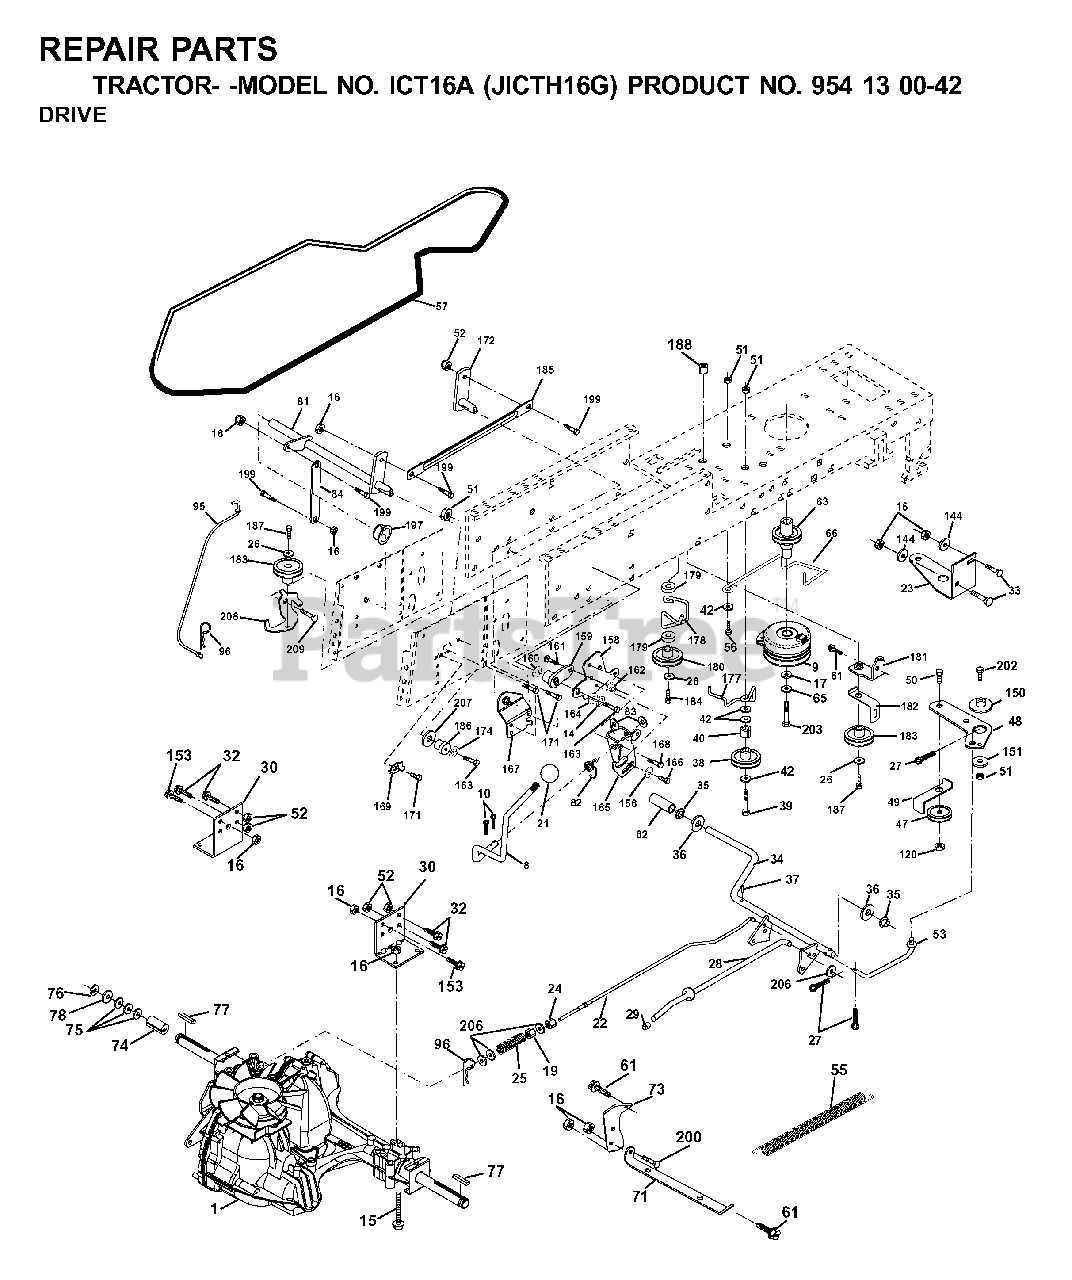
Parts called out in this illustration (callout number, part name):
8	ROD SHIFT
10	PIN COTTER
14	LOCKWASHER
15	BOLT HEX 5/16-18 GR 5
16	NUT.71038.31-18.HEX.NYLOCK
19	NUT
21	PISTOL KNOB
24	NUT
25	SPRING ROD LT
27	COTTER PIN
28	ROD BRAKE PARK LT
29	PLUNGER CAP
30	BRKT, TRNSXLE MNT 20"
32	BOLT RB
33	BOLT
35	BEARING.NYLON
36	WASHER LT
37	DRIVE PIN
38	PULLEY.FLAT
42	WASHER
47	IDLER PULLEY
48	BELLCRANK, CLUTCH
49	RETAIN BELT
50	BOLT
51	LOCKNUT
52	LOCKNUT
53	LINK, CLUTCH LT
55	SPRING, RETURN LT
61	SCREW 3/8-16X3/4
62	PEDAL COVER T
63	PULLEY, CLUTCH ELECT EVX
65	LOCKWASHER
66	KEEPER BELT ENGINE
71	STRAP TORQUE LH HYDRO
73	STRAP TORQUE RH HYDRO
74	SPACER AXLE
76	E-RING LT
77	SQUARE KEY
81	SHAFT ASSY
82	SPRING,TORSION
83	WASHER
96	RETAINER M
120	NUT LOCK FLG 3/8-16 UNC
144	WASHER
150	BUSHING.BELLCRANK.GRD.DR
151	WASHER 12/32X2X10GA
153	BOLT
156	WASHER.SRRTD.5/16
158	BRACKET
159	HUB
161	BOLT
162	NUT.CROWNLOCK.1/4
165	RP BRACKET
167	BRACKET
168	BOLT.SHOULDER.5/16-18X
169	PLATE.FASTENING.CROSS.SHAFT
174	LOCKWASHER
180	PULLEY.FLAT.IDLER
182	KEEPER BELT
183	PULLEY.V-IDLER
184	SCREW.HXWSH.3/8
187	SCREW.3/8-16
188	SNAP BUSHING T
197	NYLINER SNAP 5/8" ID
199	BOLT SHOULDER 5/16-18 UNC
200	BOLT
202	BOLT.3/8-16X1.50
206	WASHER
207	WASHER NYL
